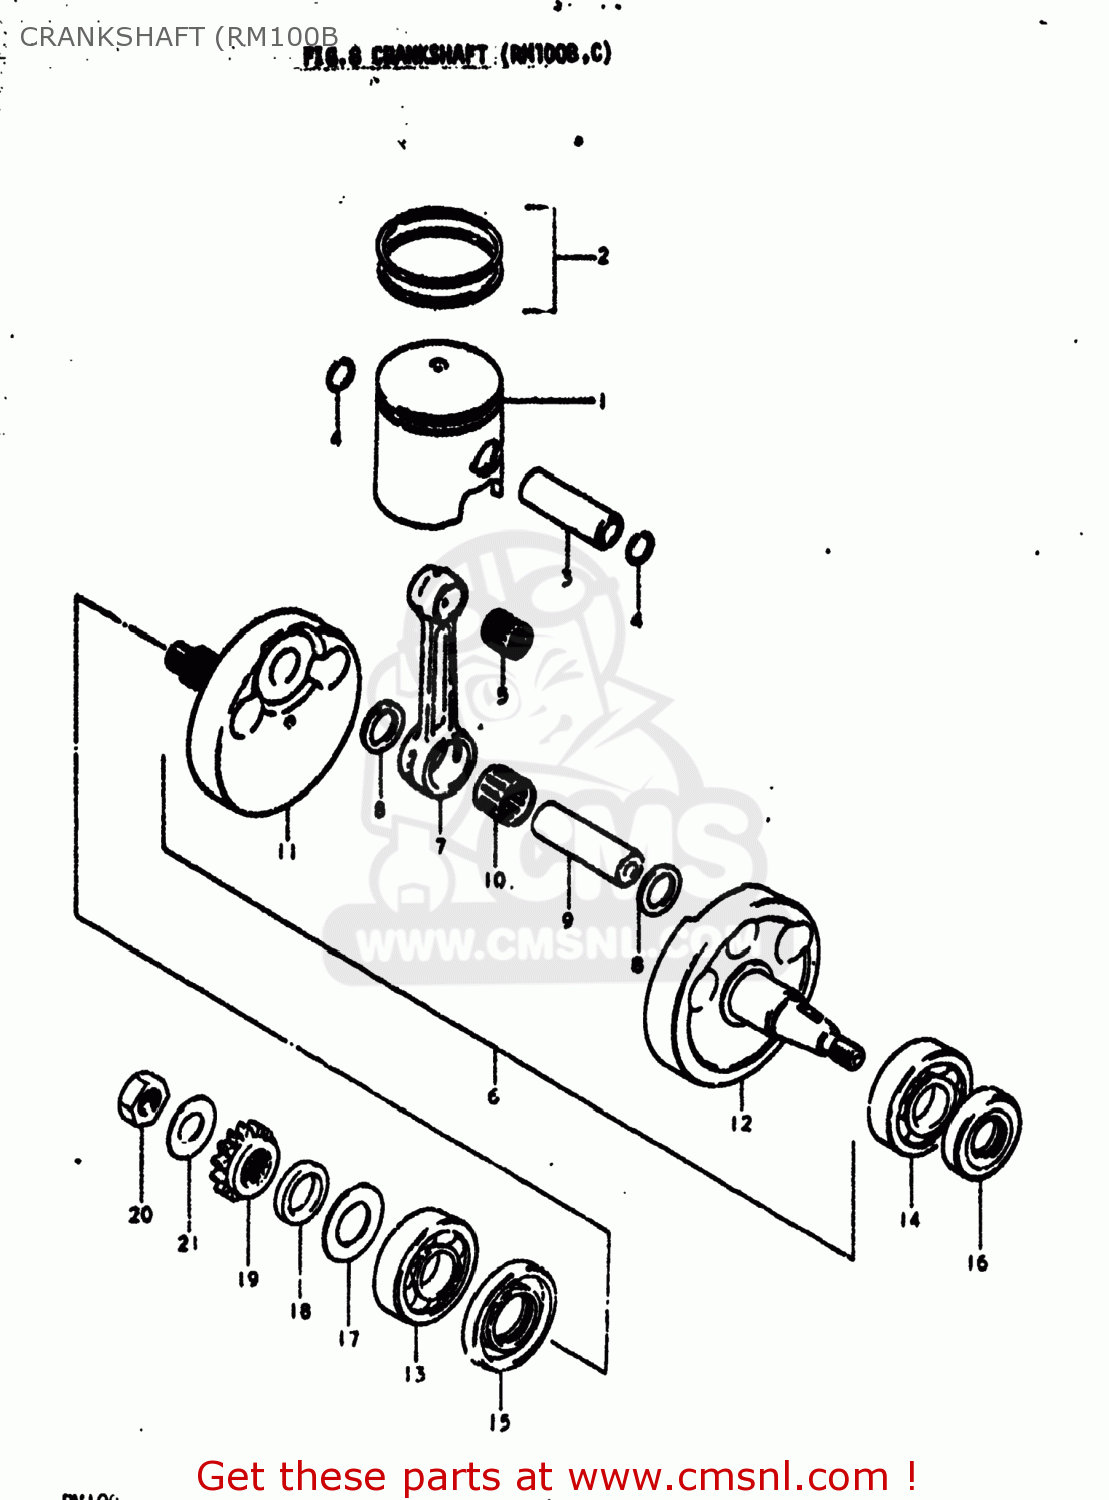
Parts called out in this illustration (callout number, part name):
1	PISTON
2	RING SET,PISTON
3	RING,PISTON
4	RING,SNAP 16MM
5	BEARING
6	CRANKSHAFT ASSEMBLY
7	ROD,CONNECTING
8	WASHER(19X32X1)
9	PIN,CRANK
10	BEARING
11	CRANKSHAFT
12	CRANKSHAFT,LEFT
13	BEARING
14	BEARING
15	SEAL,OIL(30X56X9)
16	OIL SEAL
18	SPACER
19	GEAR,PRIMARY DRIVE
20	NUT
21	WASHER
